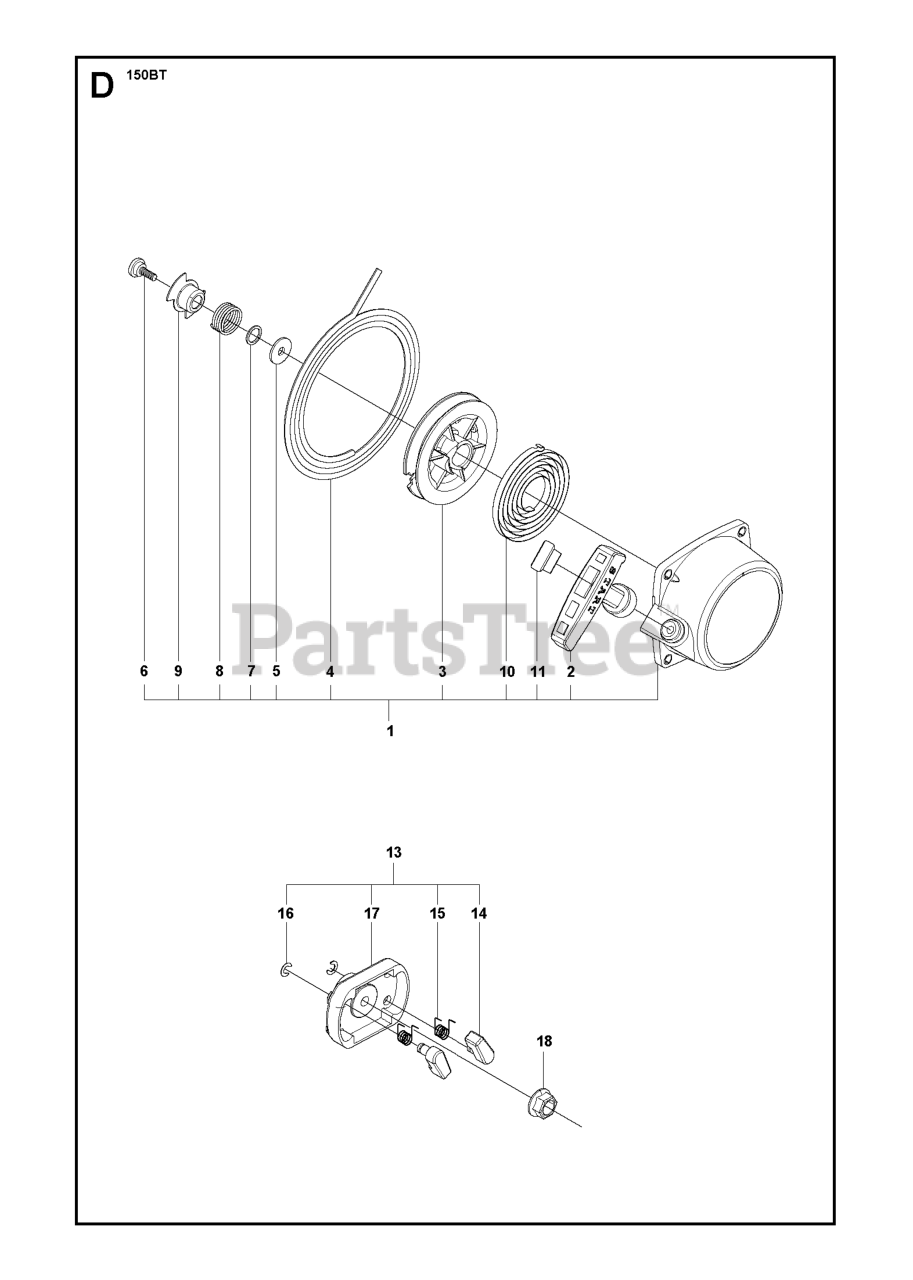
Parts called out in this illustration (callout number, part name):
1	STARTER ASSY
2	STARTER HANDLE
3	ROPE REEL
4	STARTER ROPE
5	WASHER
6	SCREW
7	WASHER
8	FRICTION SPRING
9	FRICTION PLATE
10	SPRING
11	STOPPER
13	STARTER PULLEY ASSY
14	STARTER RATCHET
15	SPRING
16	CLIP
